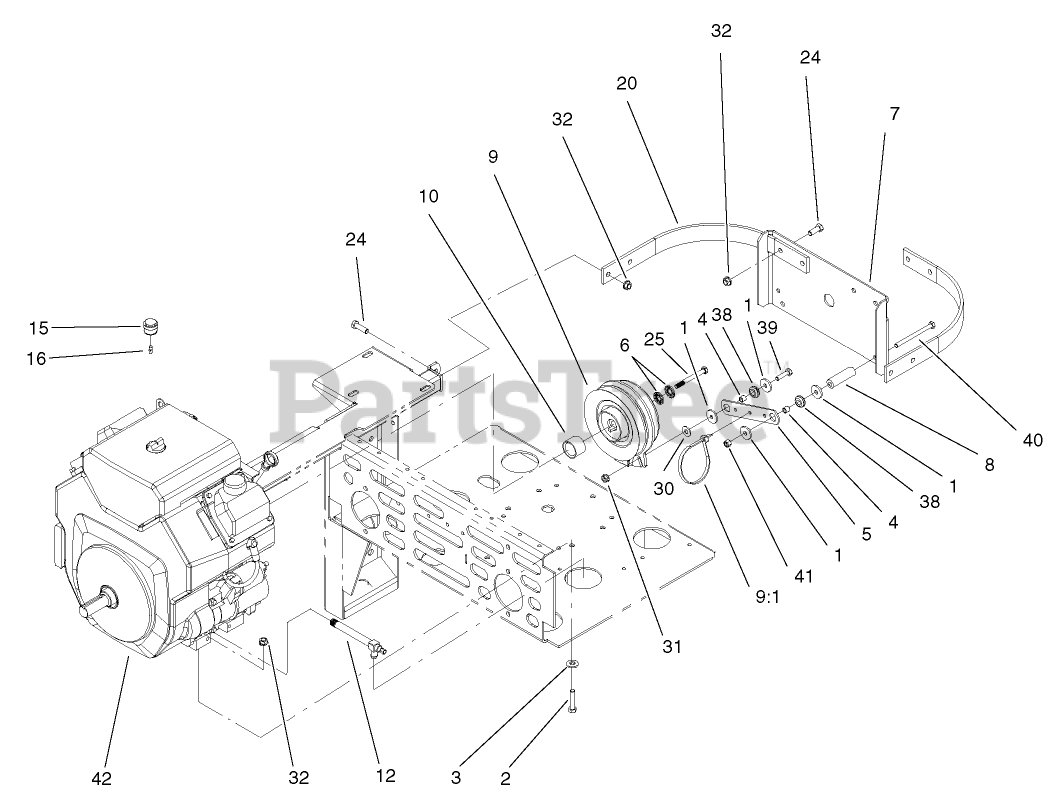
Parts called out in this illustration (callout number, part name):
1	WASHER
2	SCREW-HH
3	WASHER-BELLEVILLE
4	SPACER
5	STRAP-CLUTCH, BRAKE
6	WASHER-SPRING
7	GUARD-CLUTCH
8	SPACER-ANCHOR, CLUTCH
9	CLUTCH ASM
9:1	TIE-PLASTIC
10	SPACER-CLUTCH
12	VALVE-OIL DRAIN, LONG
15	INDICATOR-FILTER, AIR
16	ADAPTER-INDICATOR
20	BRACKET-GUARD, TOP
24	SCREW-HH
25	SCREW-HH
30	WASHER-FLAT
31	NUT-HF
32	NUT-HHF, WHIZ
38	GROMMET
39	SCREW-HH
40	SCREW-HH
41	NUT-LOCK, NI
